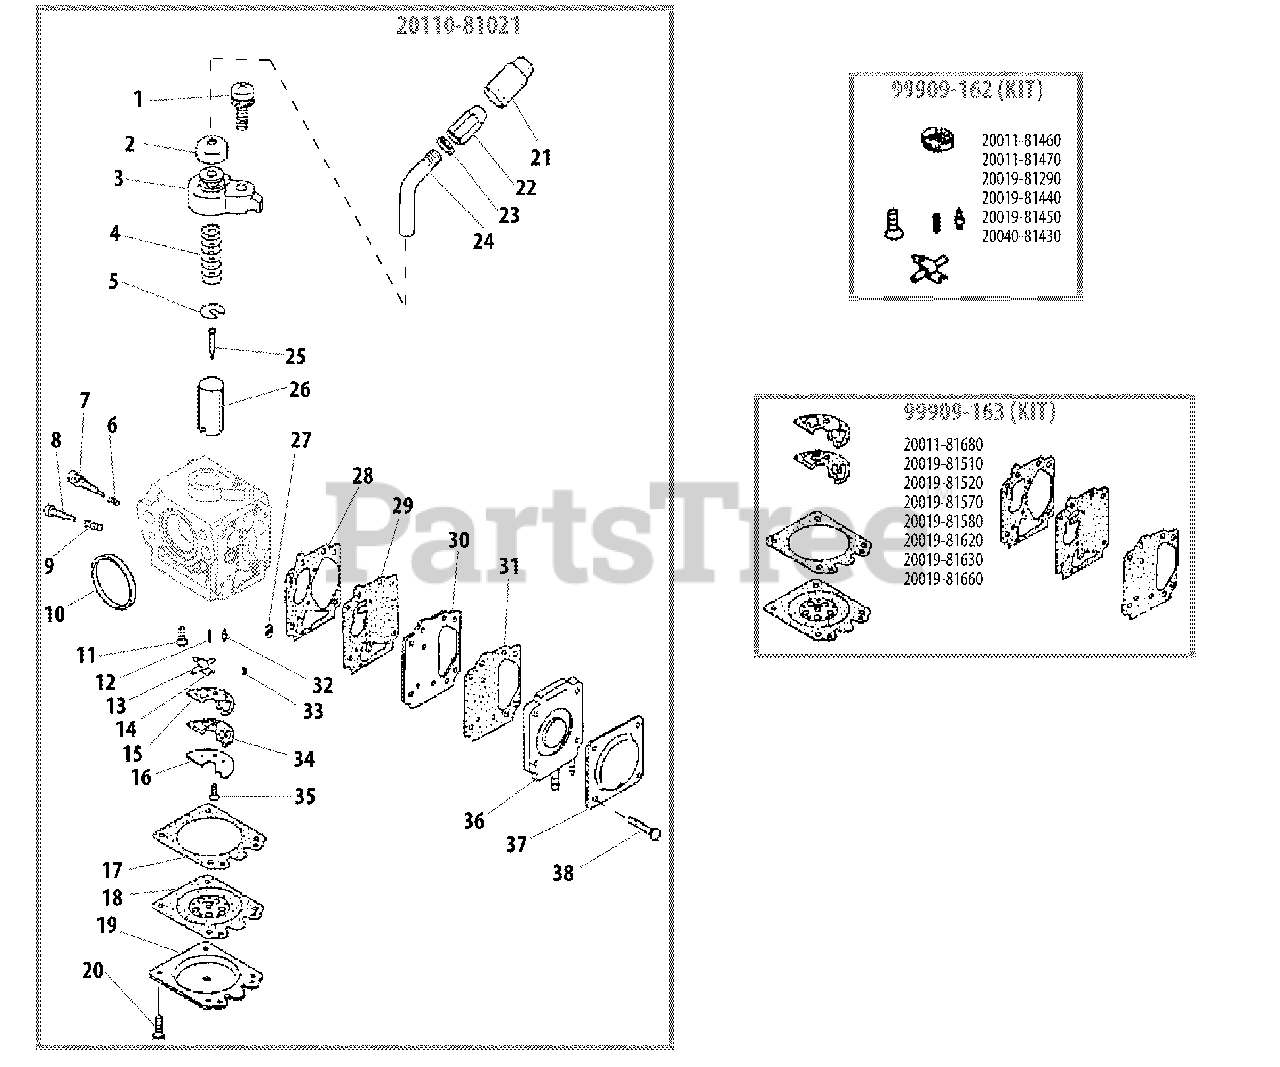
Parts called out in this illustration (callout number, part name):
1	SCREW - 5X15
2	GROMMET
3	CAP, CARBURETOR
4	SPRING, THROTTLE
5	RETAINER
6	SCREW, IDLE ADJUST
7	SCREW, IDLE ADJUST
8	SCREW, IDLE ADJUST
9	SPRING
10	SEAL
11	SCREW, METERING LEVER PIN
12	SPRING
13	PIN, METERING LEVER
14	LEVER, METERING
15	GASKET
16	PLATE
17	GASKET, METERING
18	DIAPHRAGM, METERING
19	COVER, DIAPHRAGM
20	SCREW
21	CAP, DUST
22	NUT, CABLE ADJUST
23	LOCKNUT
24	GUIDE, CABLE
25	NEEDLE, JET
26	VALVE, THROTTLE
27	STRAINER
28	GASKET, PUMP
29	DIAPHRAGM, PUMP
30	PLATE, PUMP
31	GASKET, PUMP
32	VALVE, INLET NEEDLE
33	SPRING
34	VALVE, CHECK
35	SCREW, METERING LEVER PIN
36	COVER, PUMP
37	COVER, DIAPHRAGM
38	SCREW - 3X14
A	CARBURETOR
A	REPAIR KIT
A	DIAPHRAGM/GASKET KIT
